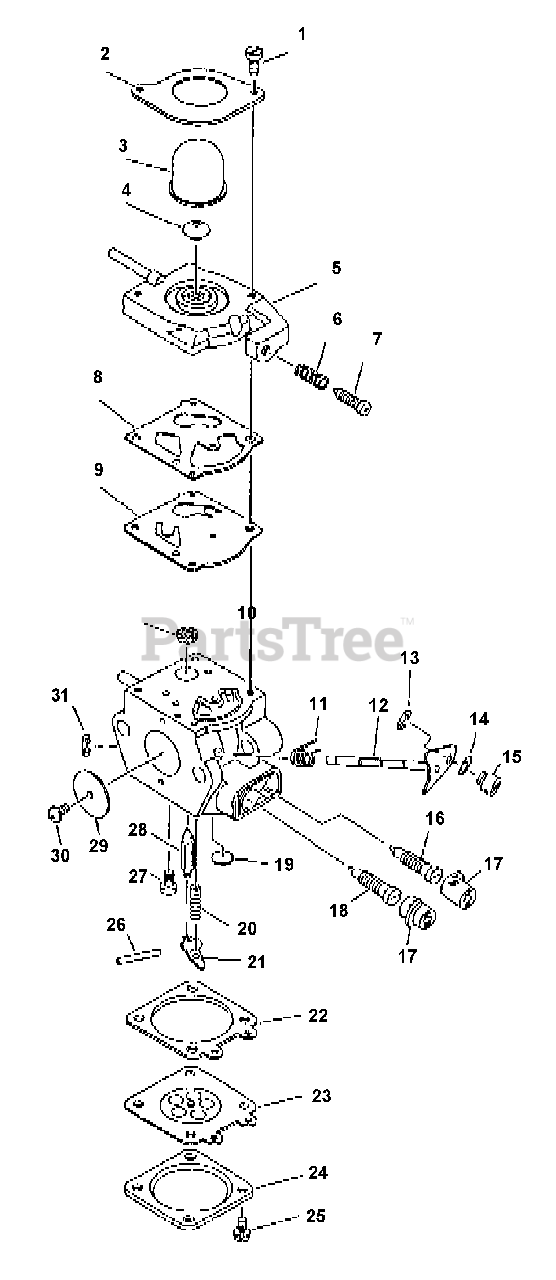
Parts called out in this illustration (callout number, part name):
1	SCREW, PUMP COVER
2	RETAINER, PURGE BULB
3	BULB, PURGE
4	VALVE, CHECK
5	BASE, PURGE
6	SPRING, IDLE ADJUST
7	SCREW, IDLE ADJUST
8	GASKET, PURGE
9	DIAPHRAGM, PURGE
10	STRAINER
11	SPRING, THROTTLE RETURN
12	SHAFT, THROTTLE
13	RING, RETAINING
16	NEEDLE - HIGH SPEED
17	CAP, LIMITER
18	NEEDLE - LOW SPEED
19	PLUG, WELCH
20	SPRING, METERING LEVER
21	LEVER, METERING
22	GASKET, METERING
23	DIAPHRAGM, METERING
24	COVER, METERING
25	SCREW
26	PIN, METERING LEVER
27	SCREW, METERING LEVER PIN
28	VALVE, INLET NEEDLE
29	VALVE, THROTTLE
31	RING, RETAINING
